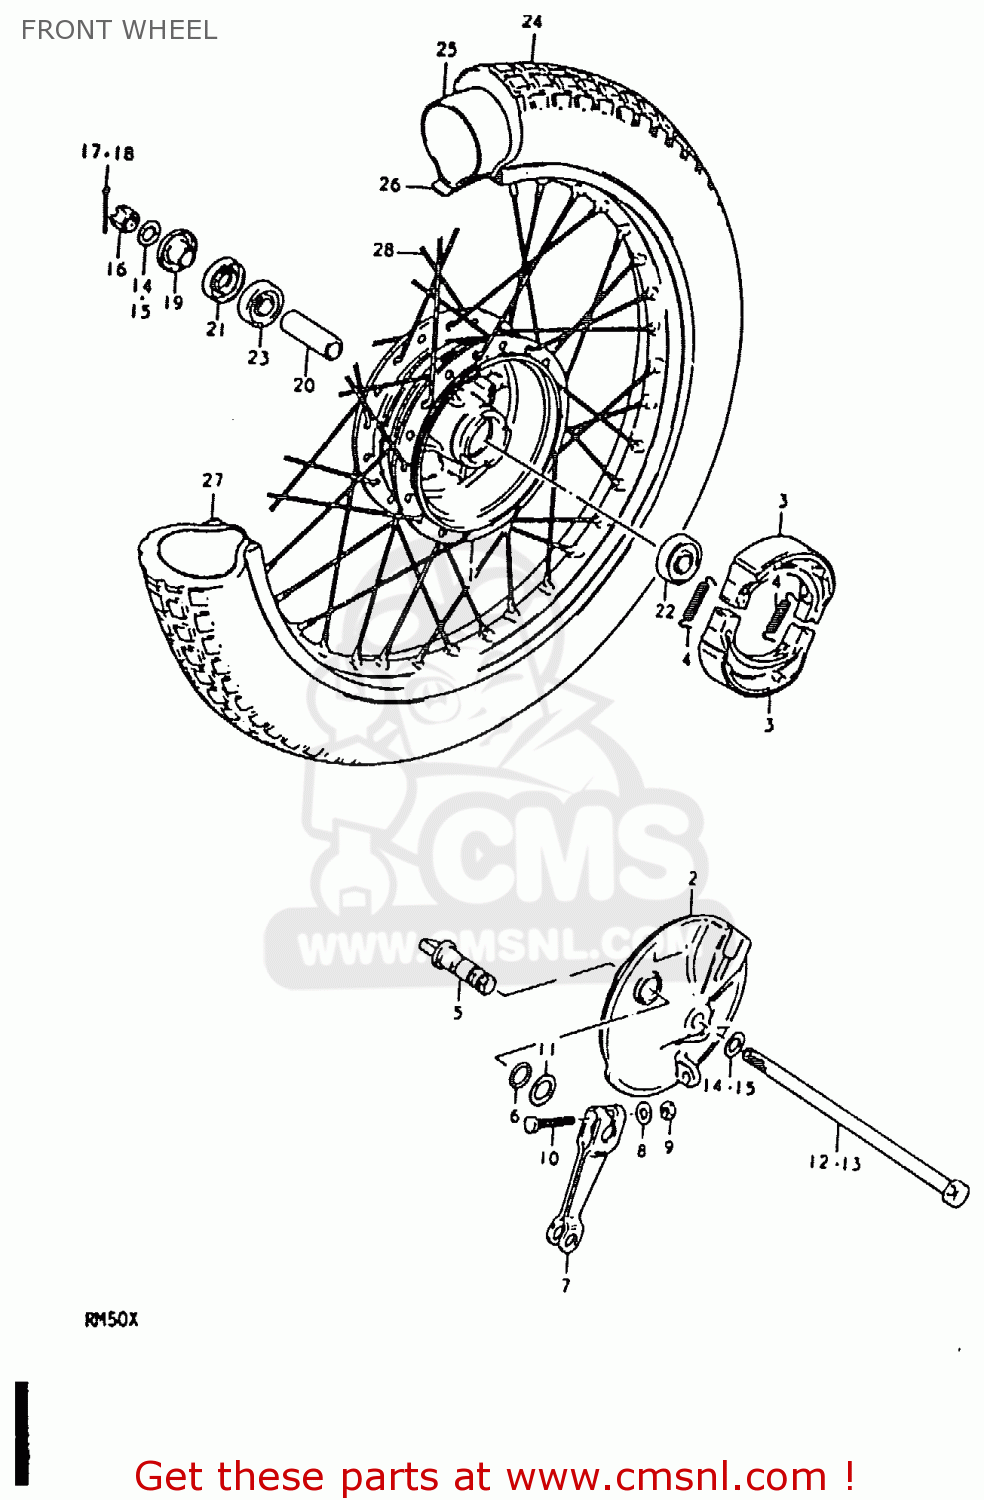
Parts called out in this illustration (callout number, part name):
1	HUB,FRONT
2	PANEL,FRONT HUB
3	SHOE,BRAKE
4	SPRING(L:34)
5	CAM,FR BRAKE
6	O RING(D:2.5,ID:11.4)
7	LEVER,FR BRAKE CAM
8	WASHER
9	NUT
10	BOLT
11	WASHER(12.5X20X1)
12	AXLE,FRONT
13	AXLE,FRONT
14	WASHER
15	WASHER(10.5X22X2.3)
16	NUT
17	COTTER PIN
18	PIN 20X20
19	SPACER,FRONT AXLE,RIGHT
20	SPACER (10.2X16X51)
21	SEAL,OIL(15X31X5)
22	BEARING
23	BEARING
24	TIRE,FRONT
25	TUBE,INNER
26	PROTECTOR,INNER TUBE
27	RIM,FRONT WHEEL (1.40X14)
28	SPOKE SET,FRONT
